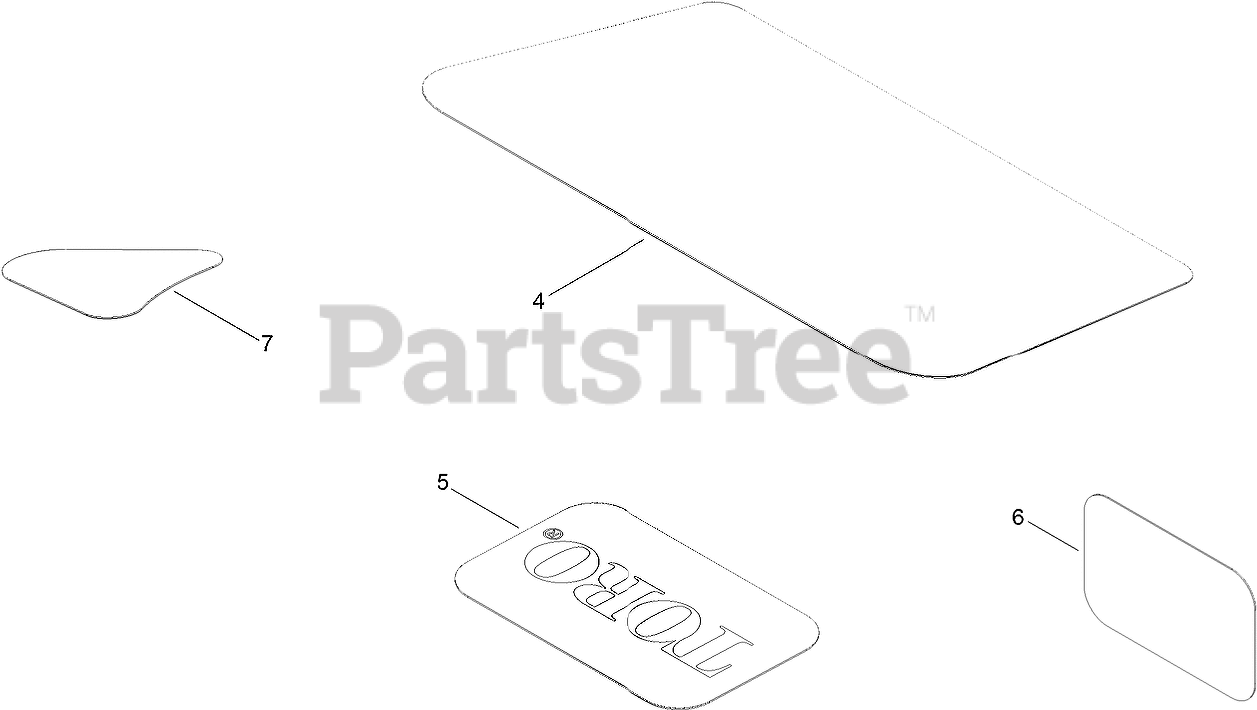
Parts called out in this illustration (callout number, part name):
4	DECAL-ENGINE
6	PLACARD-INTAKE
7	DECAL-DRAIN, OIL
